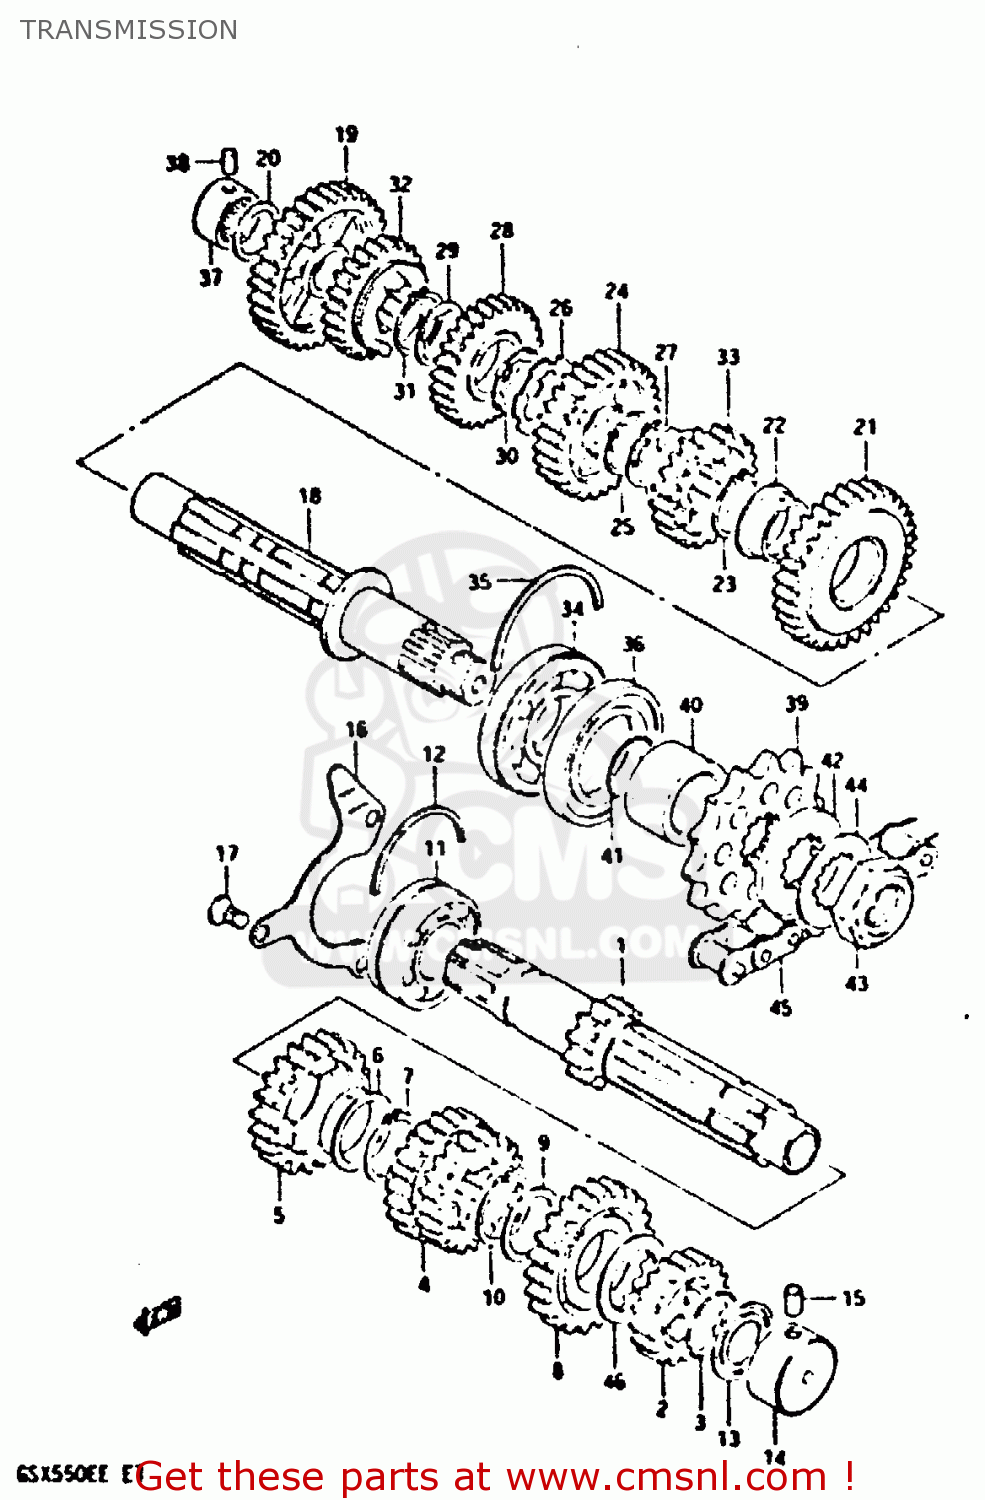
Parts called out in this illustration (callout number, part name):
1	SHAFT,COUNTER
2	GEAR,SECOND DRIVE
3	RING,SNAP
4	GEAR,THIRD/FOURTH DRIVE
5	GEAR,FIFTH DRIVE
6	BUSHING
7	RING,SNAP
8	GEAR,SIXTH DRIVE
9	WASHER,LOCK
10	RING,SNAP
11	BEARING(25X52X19.6)
12	C RING
13	SEAL,OIL(20X31.2X2.7)
14	BEARING(20X34X17.5)
15	PIN
16	PLATE,COUNTERSHAFT BEARING
17	SCREW
18	SHAFT,DRIVE
19	GEAR,FIRST DRIVEN
20	WASHER
21	GEAR,SECOND DRIVEN
22	BUSHING
23	RING,SNAP
24	GEAR,THIRD DRIVEN
25	WASHER,LOCK
26	WASHER,LOCK
27	RING,SNAP
28	GEAR,FOURTH DRIVEN
29	WASHER,LOCK
30	WASHER
31	RING,SNAP
32	GEAR,FIFTH DRIVEN
33	GEAR,SIXTH DRIVEN
34	BALL BEARING 25X62X17
35	C-RING
36	SEAL,OIL(33X62X7)
37	BEARING(20X34X20)
38	PIN
39	SPROCKET,ENGINE
40	SPACER (25X33X20.1)
41	O RING(D:1,ID:24.5)
42	SPACER
43	NUT
44	WASHER
45	CHAIN ASSEMBLY,DRIVE
46	SHIM
